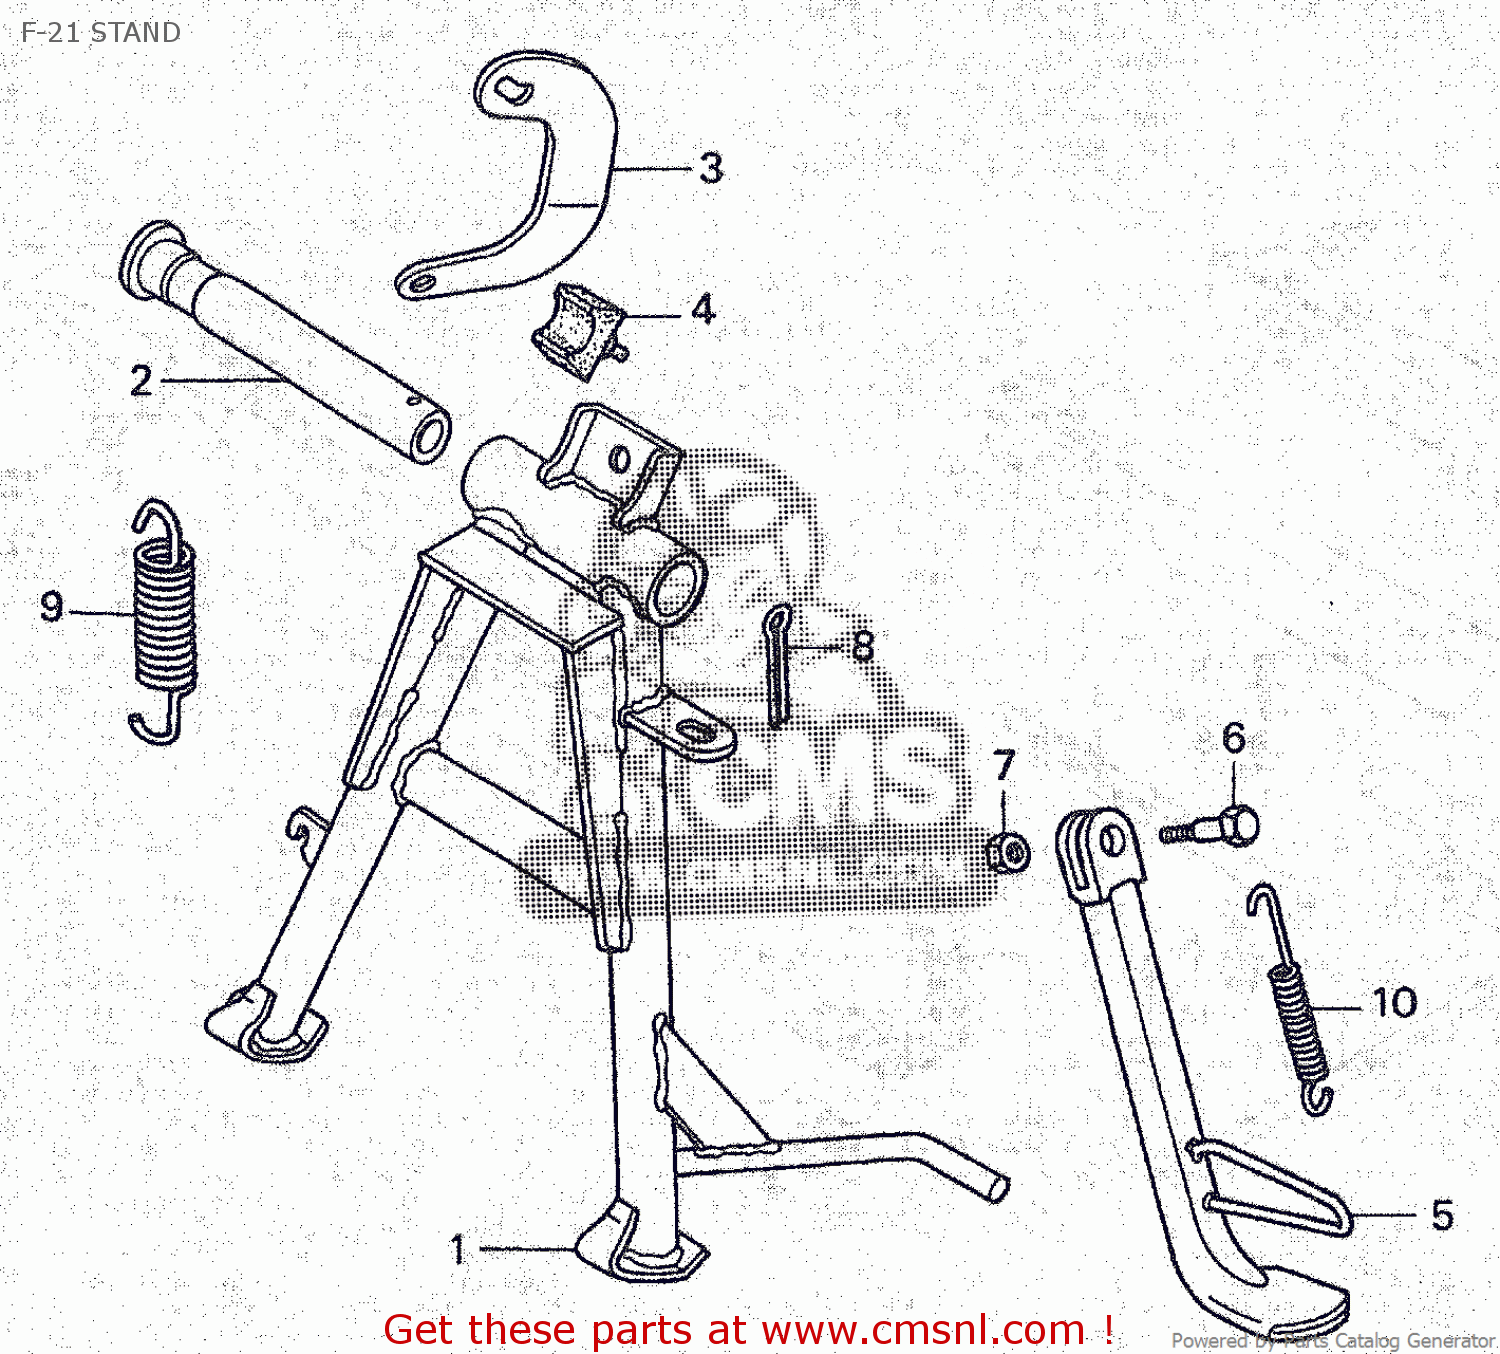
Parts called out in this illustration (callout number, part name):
1	STAND COMP,MAIN
2	SHAFT,RR BRK PIVO
3	HOOK,MAIN STAND S
4	RUBBER,STAND STOP
5	BARCOMPSIDESTAND
6	SCREW,STAND PIVOT
7	NUT,HEX.,10MM
8	PIN,SPLIT,3X25
9	SPG.A,MAIN STAND
10	SPRING,SIDE STAND
